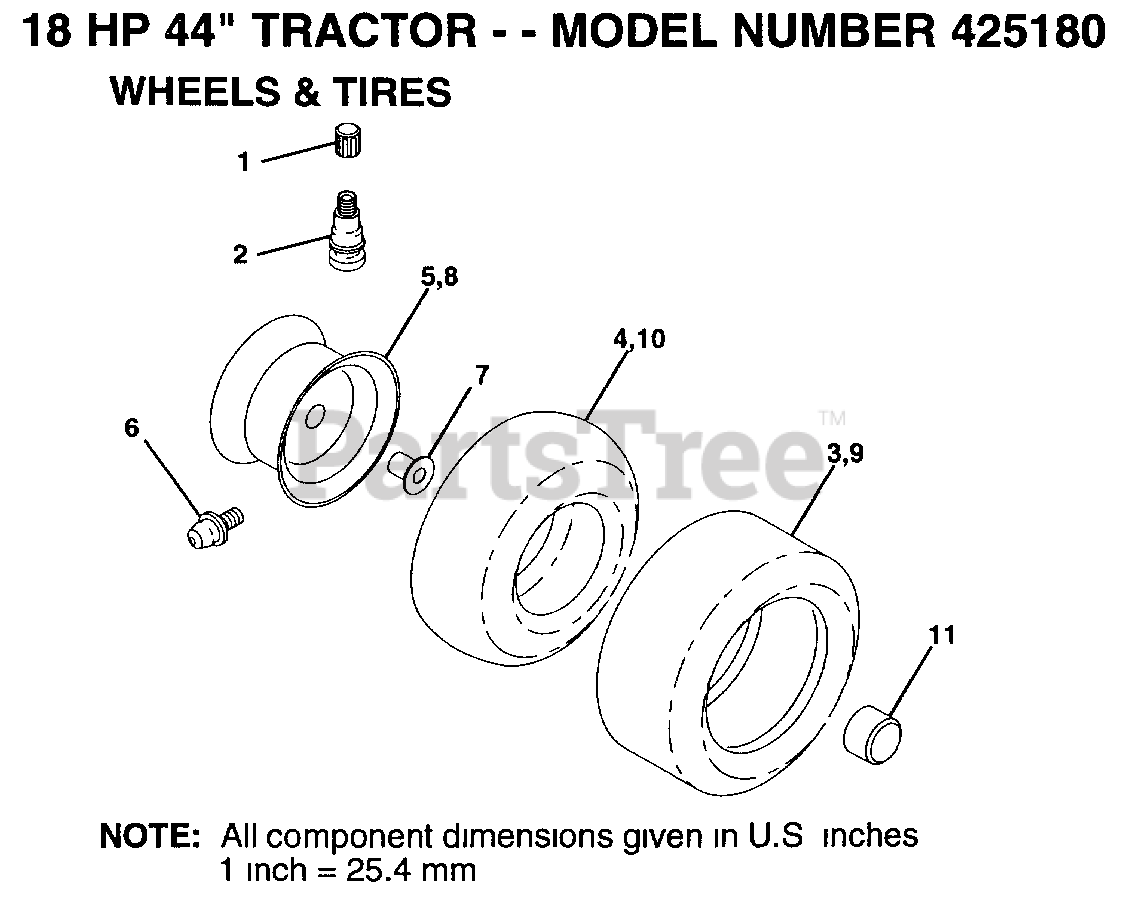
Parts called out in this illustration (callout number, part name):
1	VALVE CAP
2	VALVE STEM LT
4	TUBE.5.3/4.5/6
5	RIM.FRONT.
6	FITTING LT
7	"FLANGE, BEARING"
8	"WHEEL,REAR"
10	TUBE.23X8/10-12
11	HUB CAP
